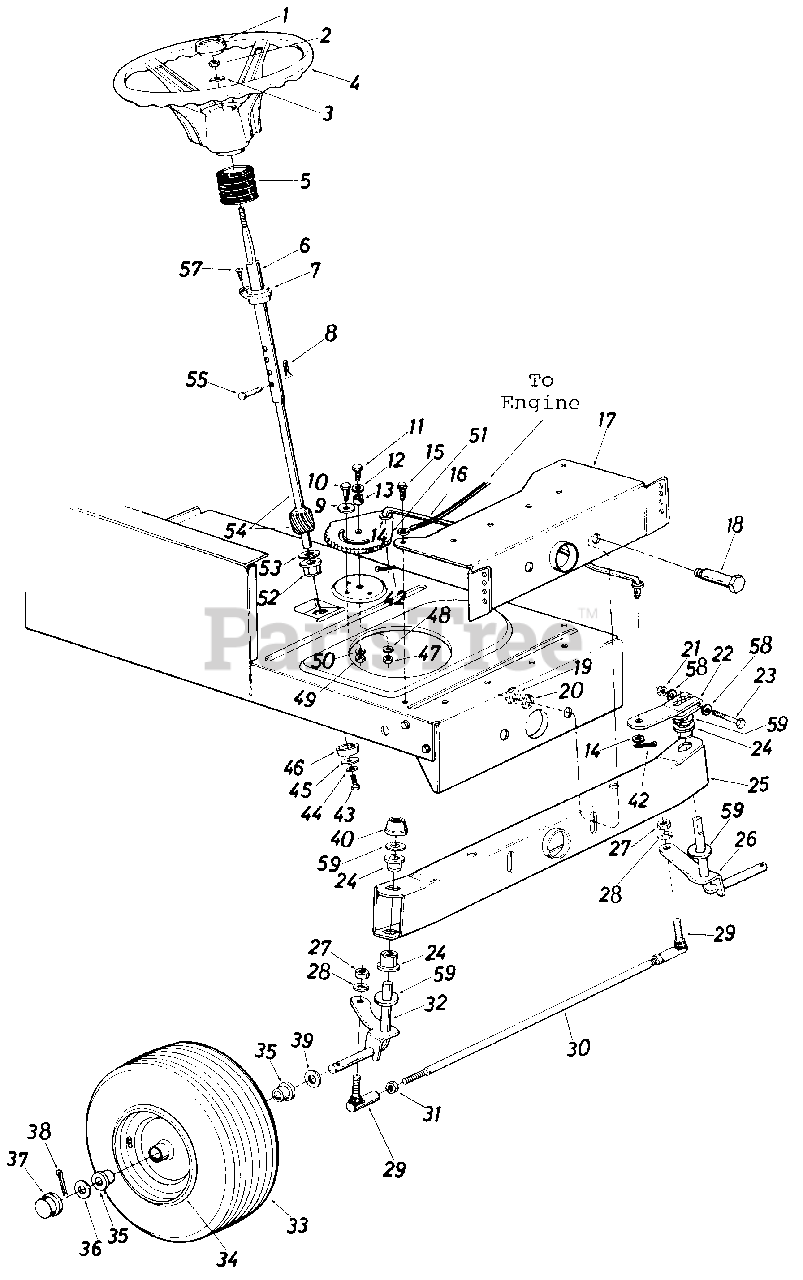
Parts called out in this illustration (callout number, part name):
1	Steering Wheel Cap
2	Hex Nut 5/16-18 Thd.
3	Belleville Wash. .345" I.D.
4	Steering Wheel 12" Dia.
5	Steering Bellow-4.5"
6	Steering Column Ass'y.
7	Flange Bearing .890 I.D. x 1.36 O.D.
8	Internal Cotter Pin 1/4" Dia.
9	Fl-Wash. .438" I.D. x 1.37" O.D.
10	Shoulder Bolt .437" Dia. x .35 Lg. 5/16-18 Thd.
11	Hex Bolt 3/8-24 x 1.0" Lg. (Grade 5)
12	Fl-Wash. .38" I.D. x 1.0" O.D.
13	Spacer.380" I.D. x .625" O.D. x .227
14	Fl-Wash. .56" I.D. x 1.0" O.D.
15	Hex Wash. Hd. Self-Tap Scr.
16	Steering Drag Link
17	Front Pivot Brkt.
18	Shoulder Bolt .498" Dia. x 2.04 Lg. 3/8-16 Thd.
19	Hex Nut 3/8-16 Thd.
20	L-Wash. 3/8" I.D.
21	Hex Cent. L-Nut 5/16-24 Thd.
22	Steering Arm Front Axle
23	Hex Bolt 5/16-24 x 2.00" Lg. (Grade 5)
24	Hex Flg. Brg. .634 I.D.
26	Front Axle Ass'y.-L.H.
27	Hex Nut 3/8-24 Thd.
28	L-Wash. 3/8" I.D.
29	Ball Joint 3/8-24 Thd.
30	Tie Rod
31	Hex Jam Nut 3/8-24 Thd.
32	Front Axle Ass'y.-R.H.
33	Wheel Ass'y. Comp.
34	Front Wheel Rim Only
35	Bearing
36	Fl-Wash. .635 I.D. x 1.59" O.D.
37	Front Wheel Hub Cap
38	Cotter Pin 1/8" Dia. x 1.25" Lg.
39	Fl-Wash. .635" I.D. x 1.20" O.D.
40	Push Cap 5/8" Dia. Rod
42	Cotter Pin 1/8" Dia. x 1.0" Lg.
43	Hex L-Bolt 5/16-18 x .62"
44	L-Wash. 5/16" I.D.
45	Fl-Wash. .344" I.D. x 1.25" O.D.
46	Spacer (Plastic)
47	Hex Nut 3/8-24 Thd.
48	L-Wash. 3/8" I.D.
49	Hex Nut 5/16-18 Thd.
50	L-Wash. 5/16" I.D.
51	Steering Gear Segment
52	Hex Flg. Brg. .634 I.D.
53	Fl-Wash. (Hardened)
54	Steering Shaft Lower
55	Clevis Pin 1/4" Dia. x 1.00" Lg.
57	Oval Hd. Cr.-Sunk Scr. #10 x 518" Lg.
58	Bell-Wash.
59	Fl-Wash. (Hardened)
